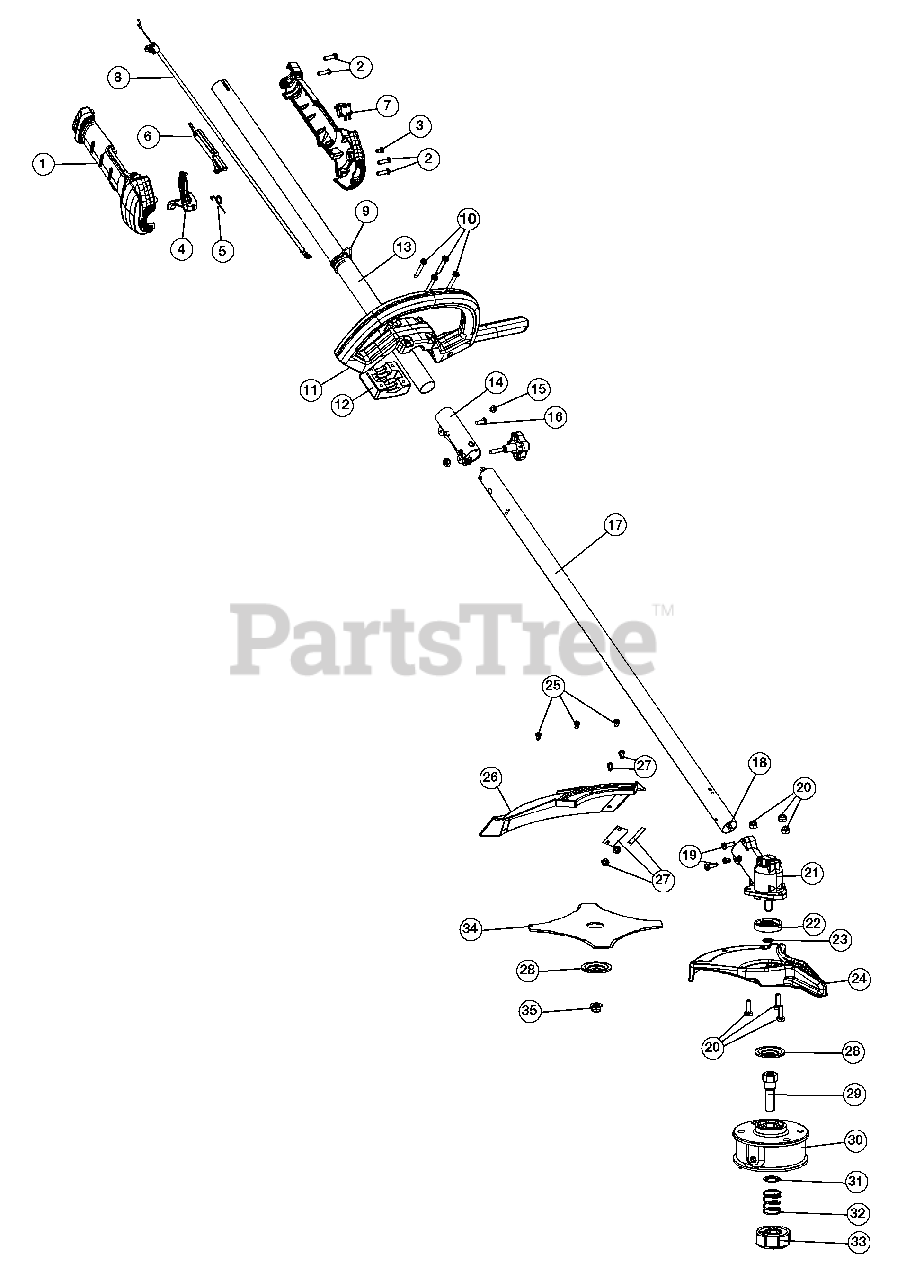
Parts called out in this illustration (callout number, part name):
1	Throttle Grip Assembly (Incl. 2 - 7)
3	Anti-Rotation Screw
4	Throttle Trigger
5	Throttle Trigger Spring
6	Lockout
8	Throttle Cable
9	Harness Clip
11	D-Handle (Incl. 10 & 12)
12	D-Handle Base
13	Upper Drive Shaft Assembly
14	Split Boom Coupler Assembly (Incl. 15 & 16)
14	Adjustment Knob
14	Knob Retaining Nut
17	Lower Drive Shaft Assembly
18	Lower Flex Shaft
19	Gearbox Mounting Hardware
20	Shield Mounting Hardware
21	Gearbox Assembly (Incl. 3 & 19)
22	Blade Driver
24	Blade Shield/Shield Mount
25	Shield Mounting Screw
26	Shield Assembly (Incl. 27)
27	Blade Assembly
28	Retaining Washer
29	Spool Shaft
30	Outer Spool Assembly
31	Retainer
33	Bump Head Knob Assembly
34	4-Tooth Blade
